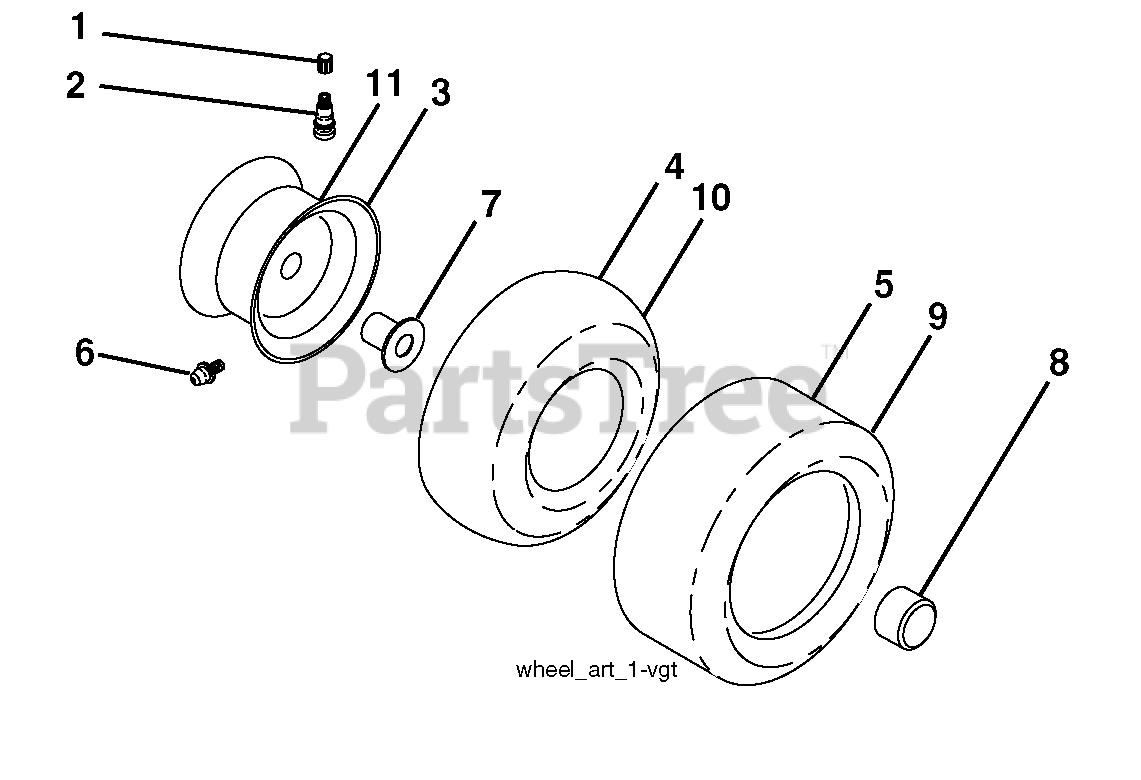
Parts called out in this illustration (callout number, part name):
1	Cap, Valve, Tire
2	Stem, Valve
3	Rim Assembly, Front
4	Tube, Front
5	Tire, Front
6	Fitting, Grease
7	Bearing, Flange
8	Cap, Axle
9	Tire, Rear
10	Tube, Rear
11	Rim Assembly, Rear
11	Sealant, Tire (10 oz. Tube)
